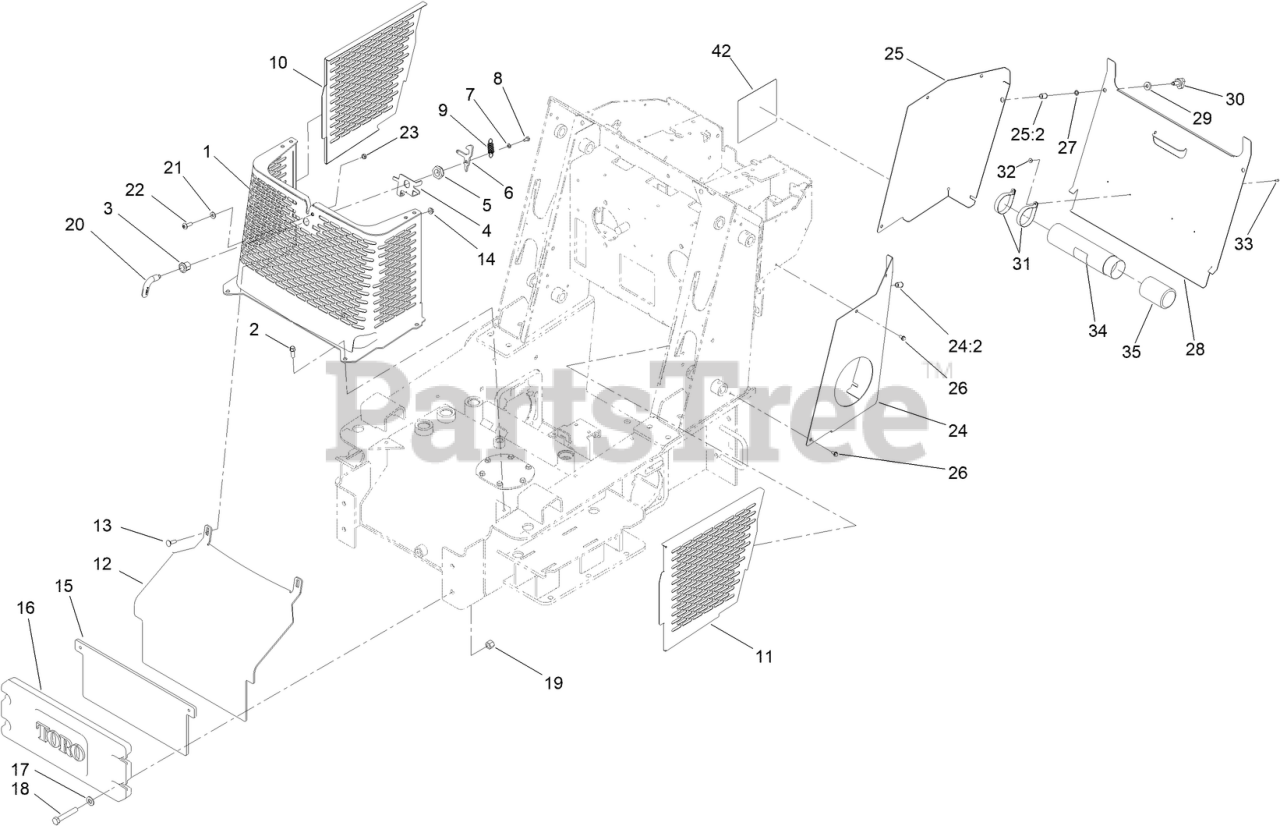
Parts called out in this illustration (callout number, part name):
2	SCREW-TAPTITE
3	HOUSING-LATCH
4	BRACKET-LATCH
5	NUT-LOCK, NI
6	CAM-LATCH
7	WASHER-LOCK
8	SCREW-HH
9	SPRING
10	PANEL-SIDE, RH
11	PANEL-SIDE, LH
12	PLATE-FRONT
13	SCREW-CARR
14	NUT-HF
15	PLATE-COUNTERWEIGHT
16	COUNTERWEIGHT-FRONT
17	WASHER-FLAT
18	SCREW-HH
19	NUT-LOCK, NI
20	HANDLE-LATCH
21	WASHER-FLAT
22	SCREW-PTH
23	NUT-LOCK, NI
24	LH REAR COVER SUPPORT ASM
24:2	NUT-CLINCH
25	RH REAR COVER SUPPORT ASM
25:2	NUT-CLINCH
26	SCREW-HWH
27	RING-RETAINING
28	COVER-ACCESS, REAR
29	WASHER-RUBBER
31	CLAMP-R
32	WASHER-BACK
33	RIVET-POP
34	TUBE-MANUAL
35	CAP-HOUSING
42	DECAL-S8VSW6X6
